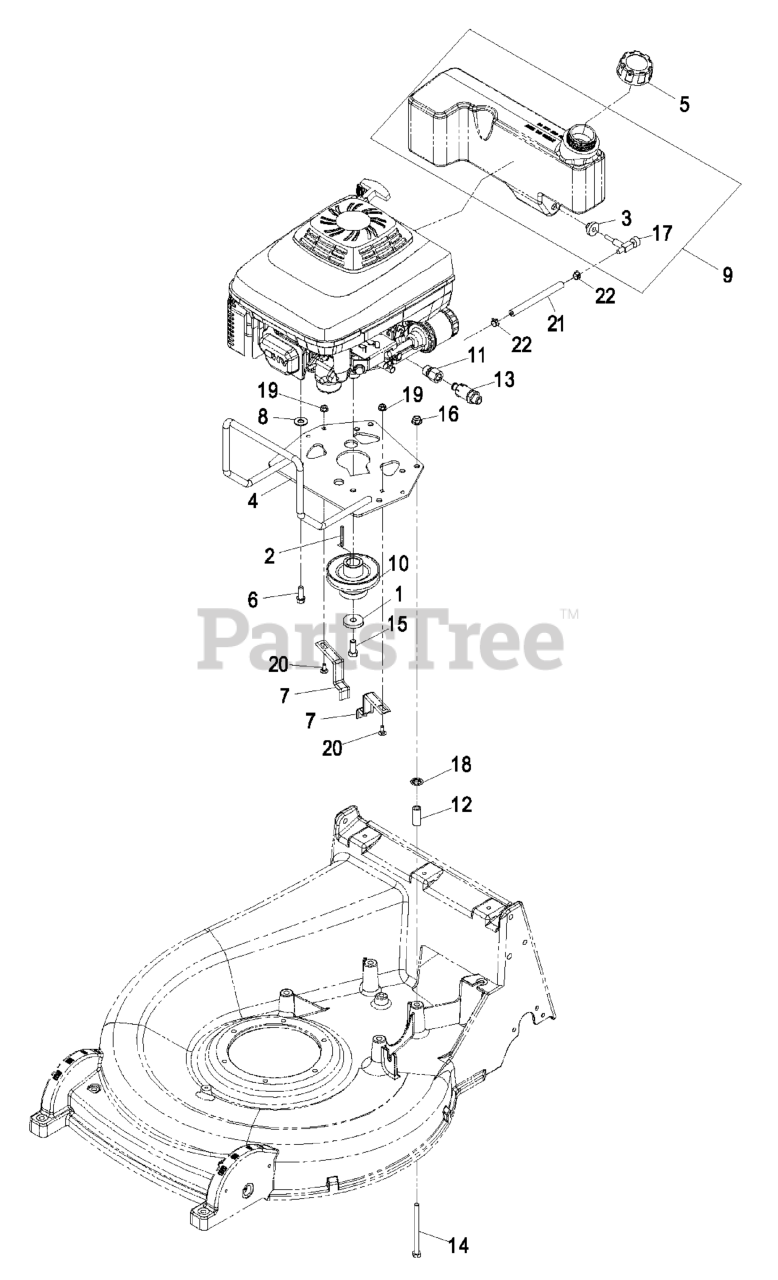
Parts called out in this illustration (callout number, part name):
1	WASHER-CLUTCH
2	KEY-SQUARE
3	BUSHING
5	CAP-GAS
6	SCREW-TAPTITE
8	WASHER-FLAT
10	PULLEY-ENGINE
11	ADAPTER
12	BUSHING-LEVER, LIFT
13	VALVE-DRAIN, OIL
14	SCREW-HH
15	SCREW-HH
16	NUT-HF, NI
17	VALVE-FUEL
18	RING-RETAINING
20	SCREW-CARR
21	HOSE-FUEL
22	CLAMP-HOSE
